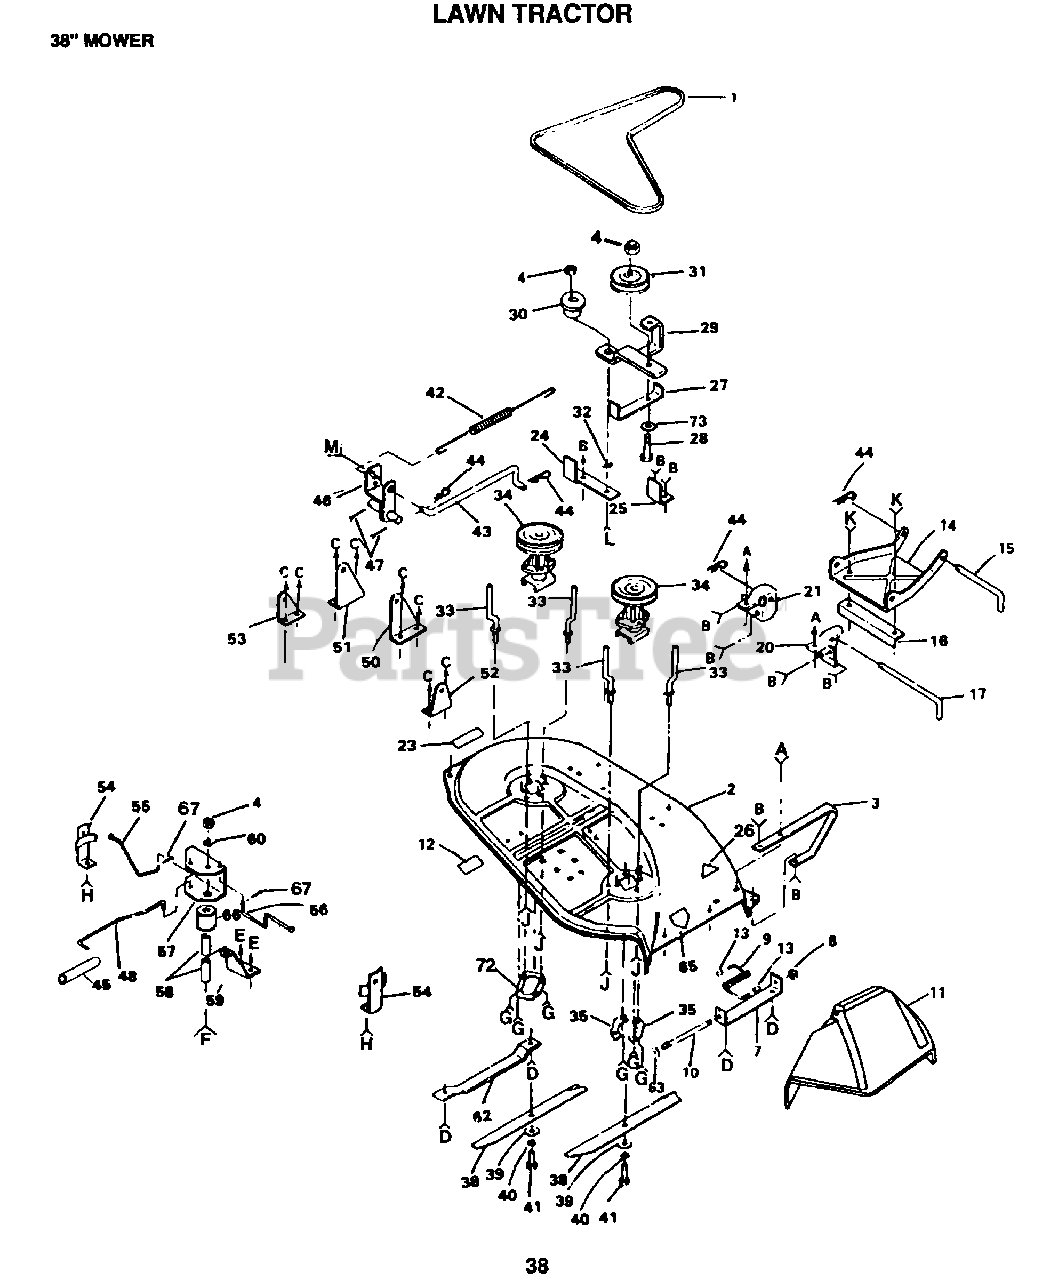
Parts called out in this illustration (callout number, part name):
1	BELT-V.79.1.MWR
5	WASHER M
6	BOLT
8	NUT PUSH M
10	ROD-HINGE T
11	DEFLECTOR-SHLD T
12	DECAL.LT
13	CAP-SLEEVE LT
14	LINK.PARALLEL
15	"ROD, FRT. PARAL T"
16	LINK STOP
17	HINGE PIN T
20	BRACKET RH LT
21	BRACKET LH T
22	BOLT
23	DECAL YT
24	SUPPORT ARM T
25	STOP T
30	SPACER RETAINER
31	PULLEY IDLER
32	"WASHER, WEAR LT"
33	BELT KEEPER LT
34	"JACKSHAFT.38""LT"
35	SUPPORT PLATE LT
36	SCREW
37	SCREW
38	"BLADE.38"" HI-LI"
39	WASHER
41	BOLT.3/8-24X1-1/2
44	SPRING.RETAINER
45	SPACER T
48	ROD BRAKE LT
49	BOLT
52	"BRKT,SUSP RH T"
53	"BRKT,SUSP REAR LH"
54	BRAKE LT
55	"ROD, BRAKE LH LT"
56	ROD BRAKE LT
57	"BRK,BRAKE,PVT LT"
59	BRACKET SUPT LTV
60	WASHER
61	BOLT
62	RUNNER-LH M
63	WASHER
64	BOLT.3/8-14X1.25
65	DECAL WARNING
69	BOLT LT
70	WASHER T
72	SUPPORT T
73	WASHER
